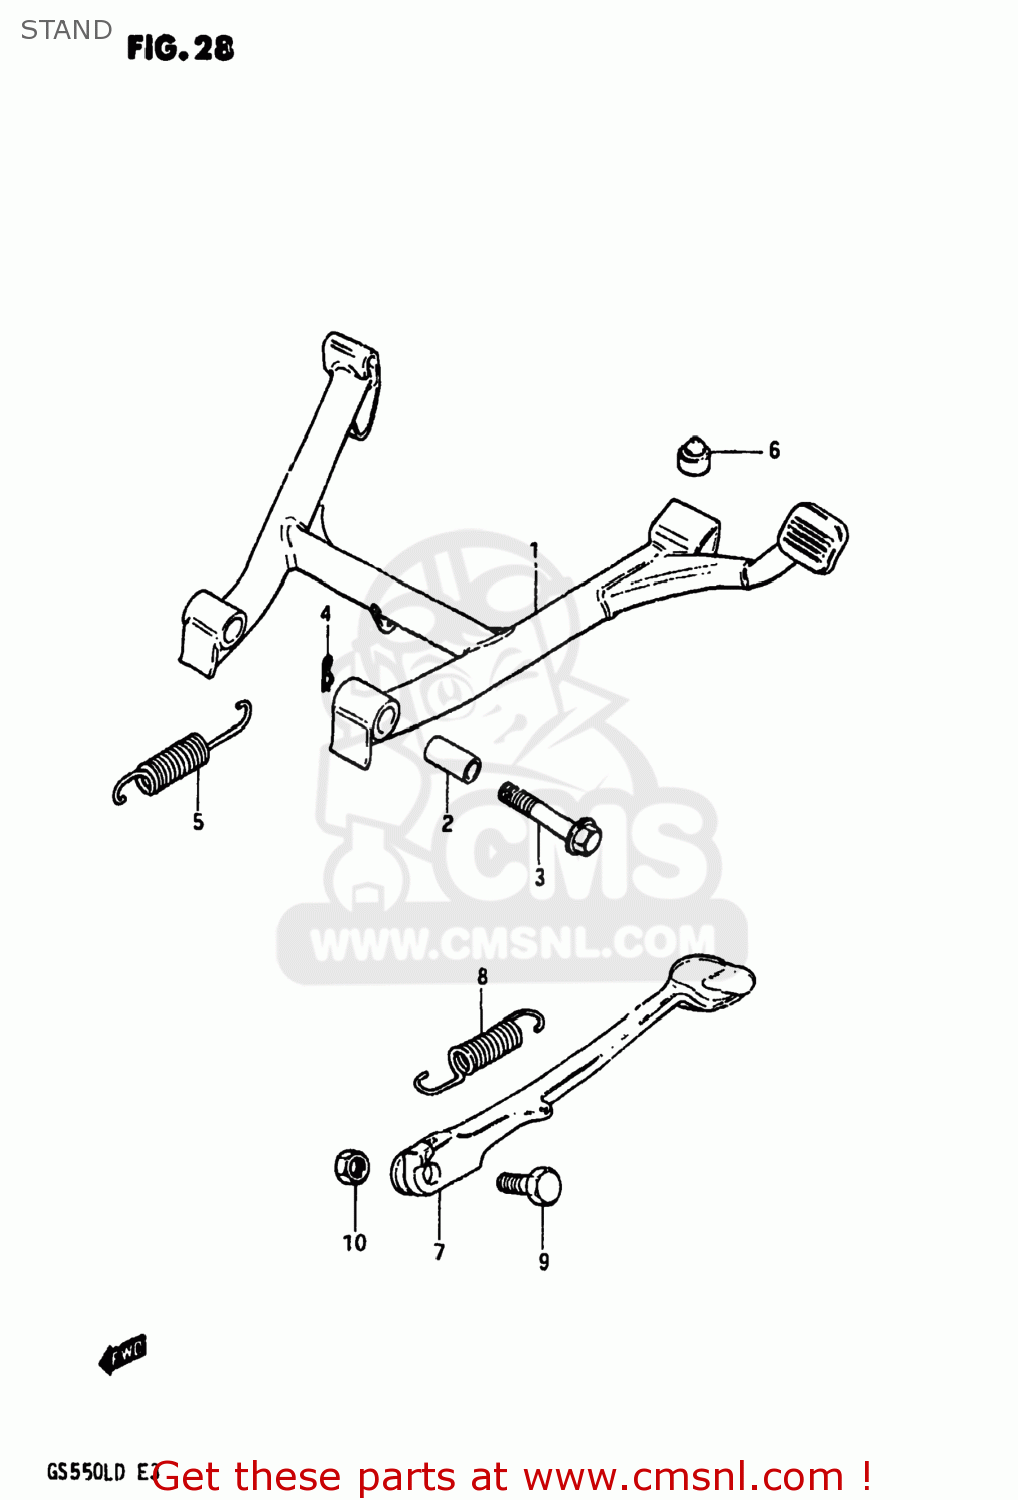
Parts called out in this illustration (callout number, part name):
1	STAND,CENTER
2	SPACER (10.5X16X31.8)
3	BOLT 10X50
4	CLIP
5	SPRING
6	CUSHION
7	STAND,SIDE
8	SPRING
9	BOLT L:30
10	NUT
